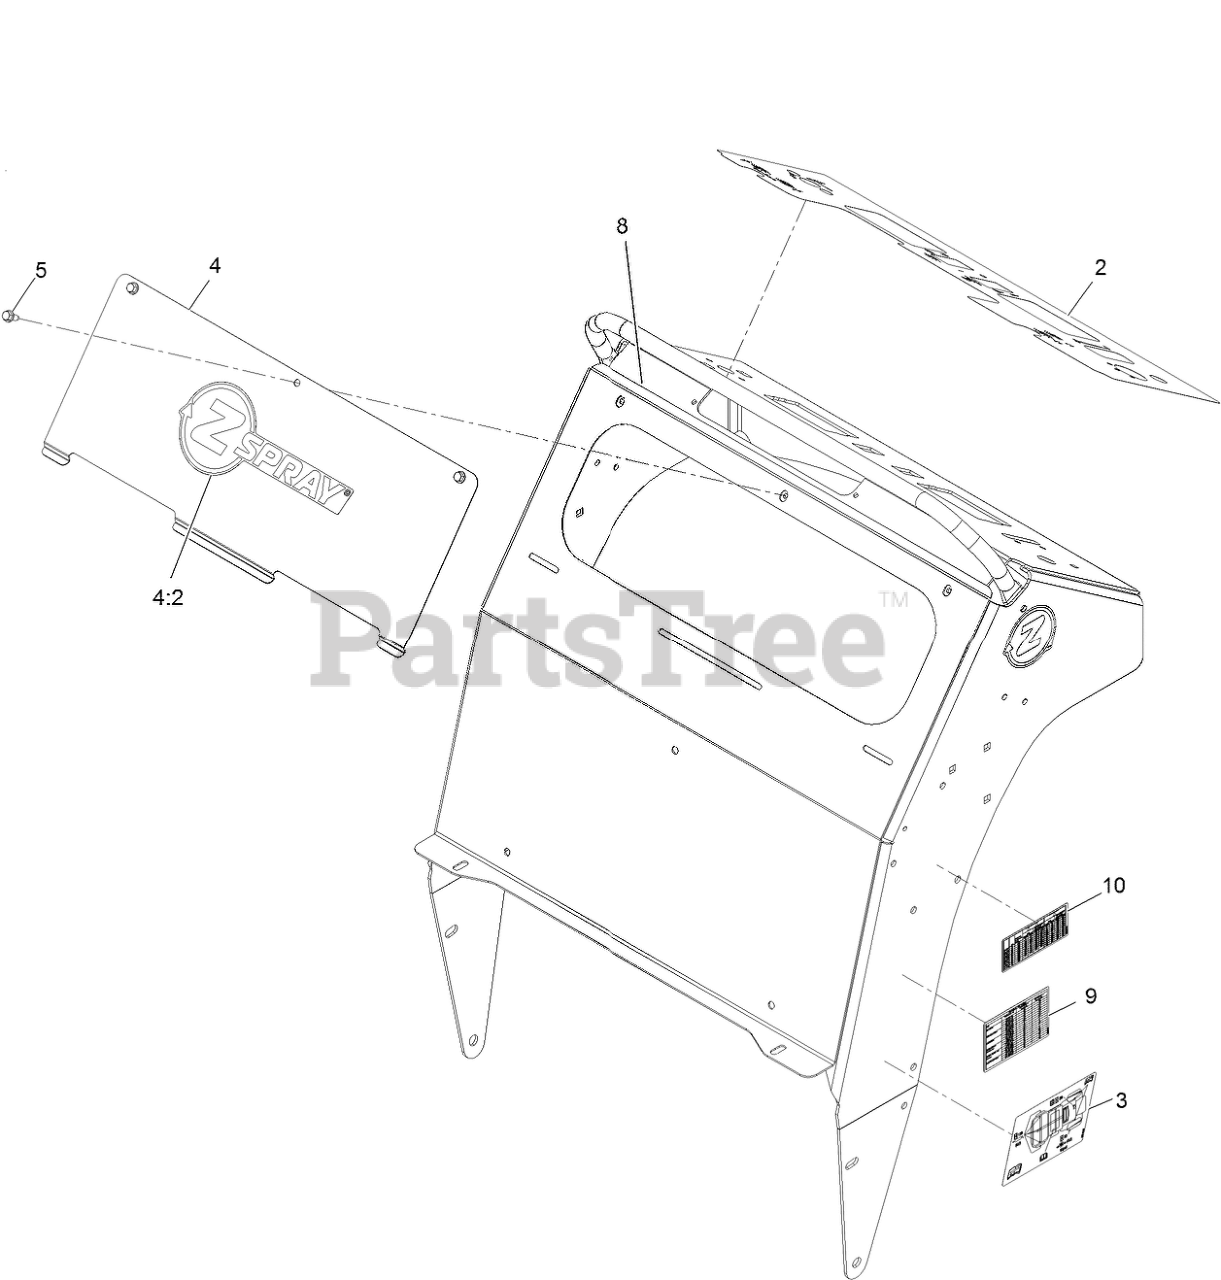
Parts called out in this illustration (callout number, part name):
2	Decal-Control
3	DECAL-SERVICE AID
4	Access Panel W/ Decal
4:2	Decal-Z-Spray
5	SCREW-HWH
8	Decal-Z-Logo
9	Decal-Spread Chart
10	Decal-Spray Chart
